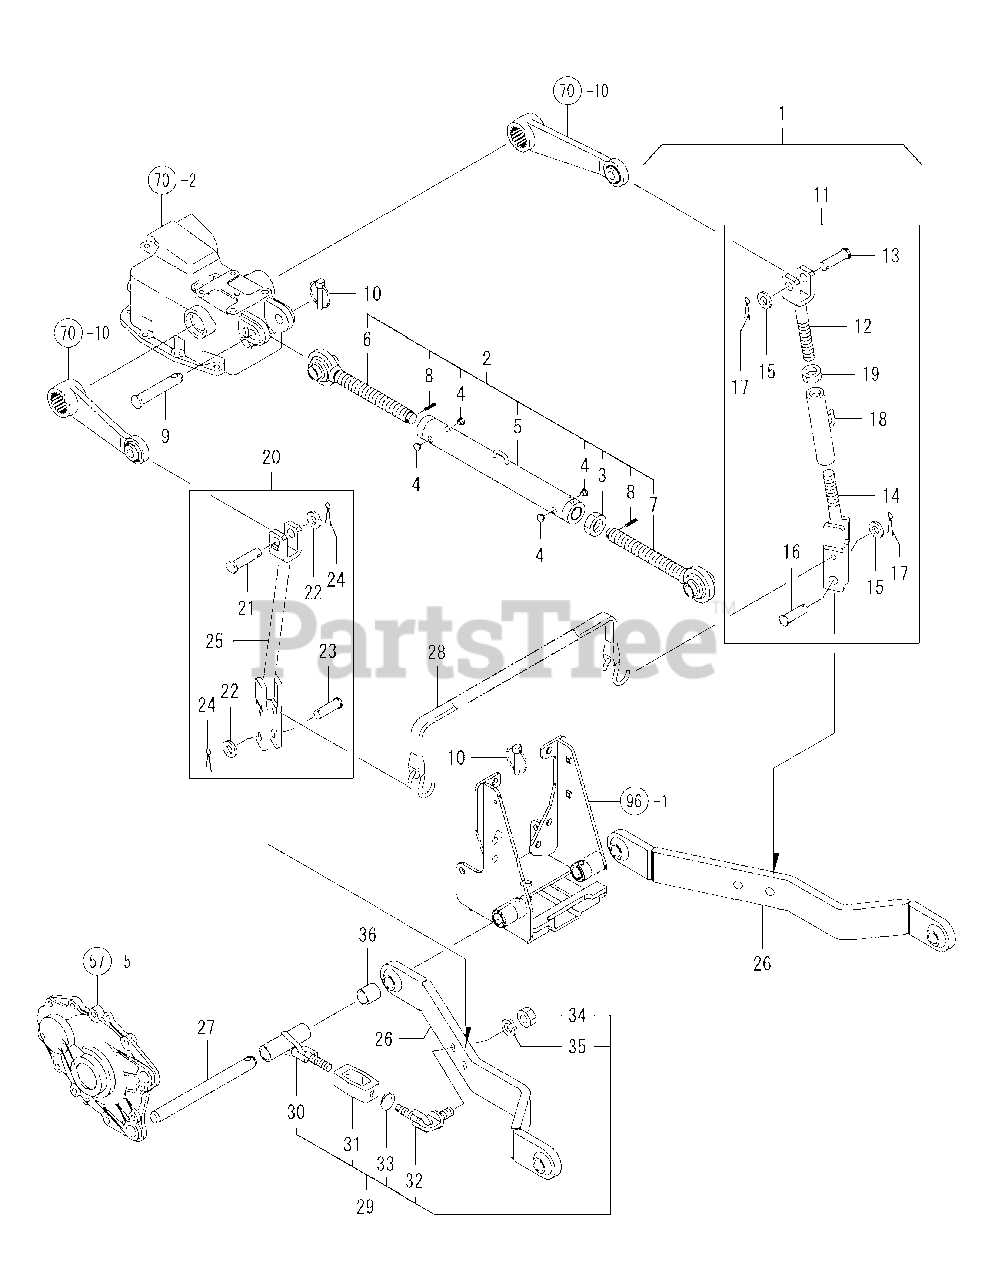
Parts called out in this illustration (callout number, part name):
2	Link, Assy Upper
6	Eye Bolt LH Assy
8	Spring Pin 5X25
9	Pin, Upper Link
10	Pin Assy, Lintch
11	Lift Link R.H. Kit
12	Upper End Assly
14	Lower End Assly
20	Link Assy, Lift L
25	Lift Link L Cmp
28	Strap, Lower Link
29	Chain Assy, Sway
35	Spring Washer 16
36	Collar, Hinge Pin
